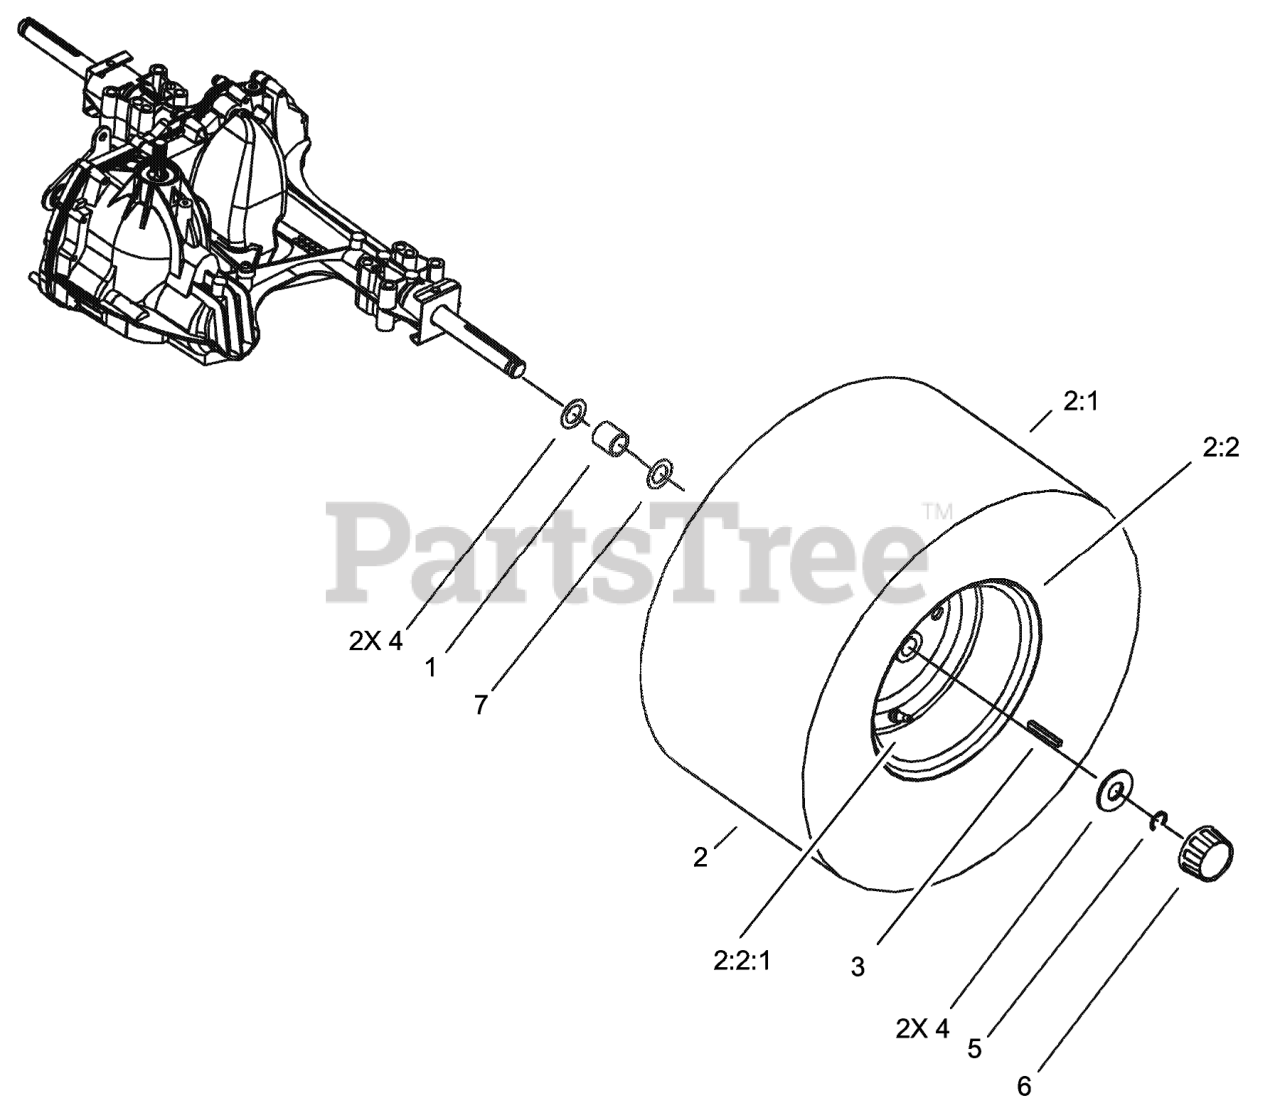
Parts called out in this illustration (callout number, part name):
1	SPACER-WHEEL
2	REAR WHEEL & TIRE ASM
2:2:1	STEM-VALVE
3	KEY-SQUARE
4	WASHER-PLAIN
5	E-RING
6	CAP-HUB
7	WASHER-THRUST
